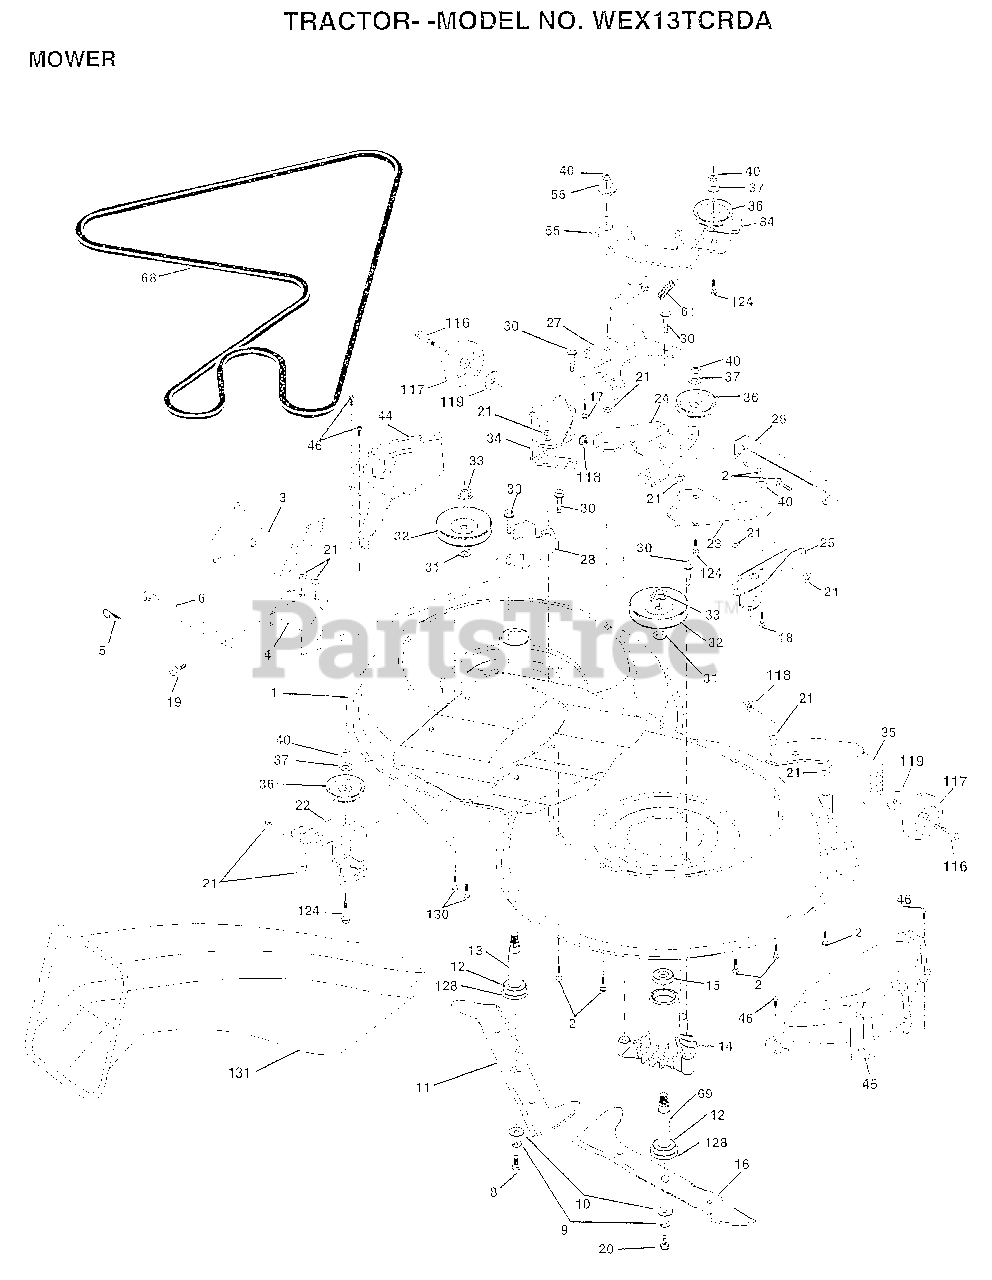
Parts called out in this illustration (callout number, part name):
1	HOUSING.ASM.MOWER
2	BOLT
3	BRKT.ASM.S-BAR.CHASSIS
4	BRKT.BAR.SWAY.DECK
6	BAR.SWAY.92.CRD
8	BLADE BOLT
10	WASHER.HARD.BLADE
11	BLADE.3-1.LH.92.CRD
12	BEARING.BALL
14	HSG ASM MANDREL
15	BEARING
16	BLADE.3-1.RH.CRD.92
17	BOLT.3/8-14X1.25
18	BOLT D
19	BOLT SHD 5/16-18
20	BOLT.3/8-24X1.25
22	BRKT.IDLER.SPRT.CRD
23	"BRKT.IDLER.SPRT.RF.92,CRD"
24	BRKT.SUSP.LF.92.CRD
25	BRKT.SUSP.RF.92.CRD
26	BRACE.SUPT.SUSP.FRT.CRD
27	BRKT.ASM.SUSP.RR.92.CRD
28	BRKT.ASM.SUSP.LR.92.CRD
30	"SCREW-THD ROLL,WA"
31	WASHER
32	PULLEY.MAND.36/46
34	BRKT.GUAGE.WHL.LF.92.CRD
35	BRKT.GUAGE.WHL.RF.92.CRD
36	PULLEY.IDLER.4.25
37	WASHER
44	COVER.MANDREL.LH.92.CRD
45	COVER.MANDREL.RH.92.CRD
46	SCREW.1/4-20X5/8
55	ARM.IDLER.92.CRD
56	SPACER RETAINER
61	SPRING.TENSION.BELT
68	HEX-BELT.92.MWR.105AA
69	SHAFT.ASM.W/LWR.BRG.RH.THD
84	"KEEPER-BELT,IDLER"
116	BOLT.SHOULDER
117	WHEEL GAGE DONUT
118	LOCKNUT
119	WASHER
124	BOLT.3/8-16X1.50
128	WASHER.FELT.
131	CHUTE.BAGGER.CRD
